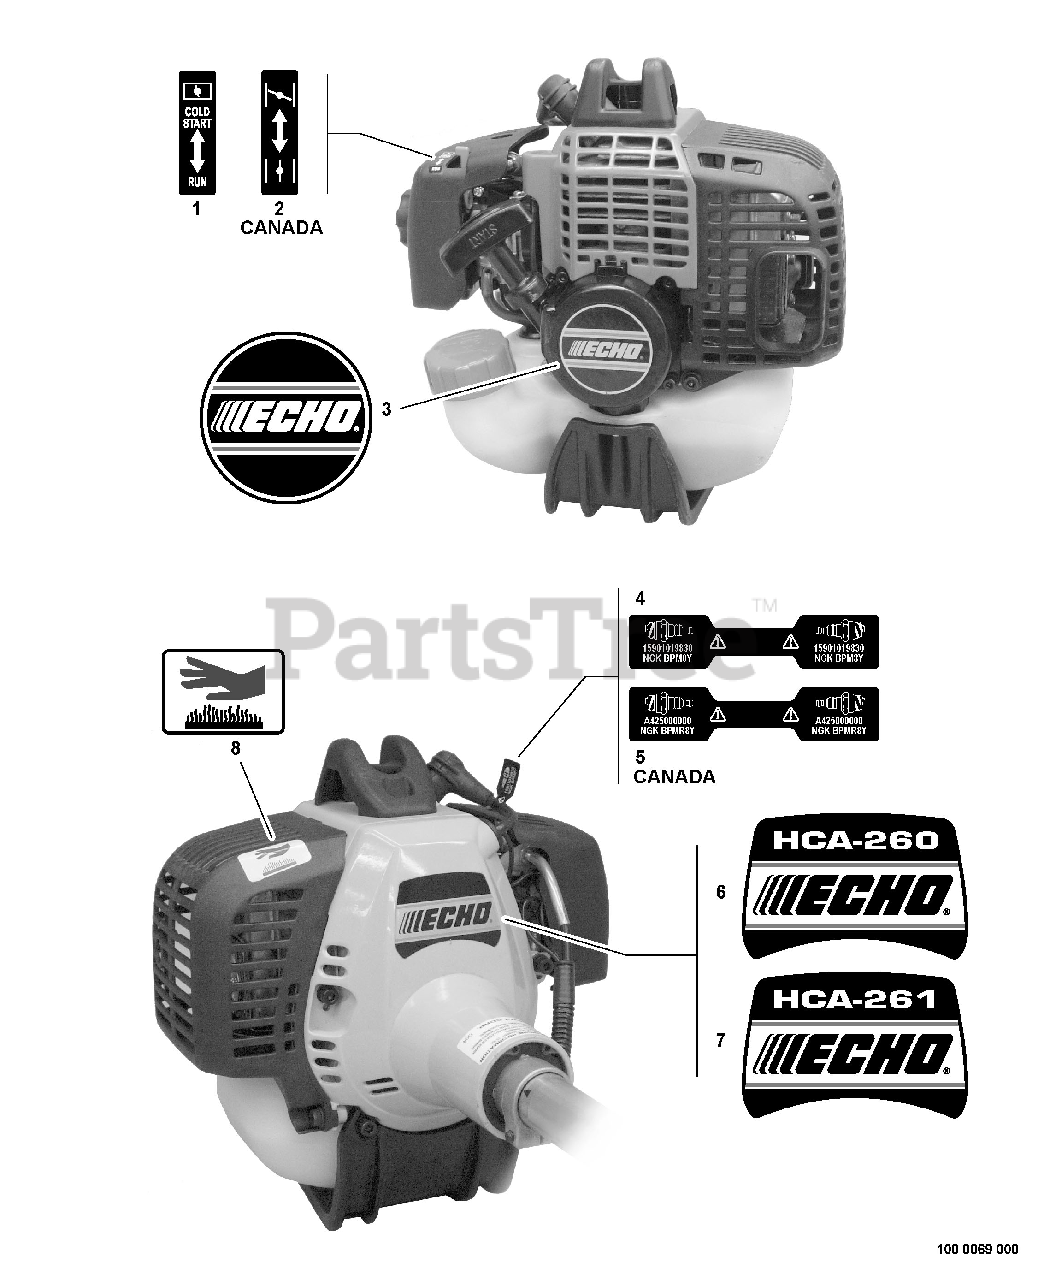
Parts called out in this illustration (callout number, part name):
1	LABEL - CHOKE
2	LABEL - CHOKE
3	LABEL - ECHO
4	LABEL - SPARK PLUG -- BPM-8Y
5	LABEL - SPARK PLUG -- BPMR-8Y
6	LABEL - MODEL HCA-260
7	LABEL - MODEL HCA-261
8	LABEL - HOT SURFACE
